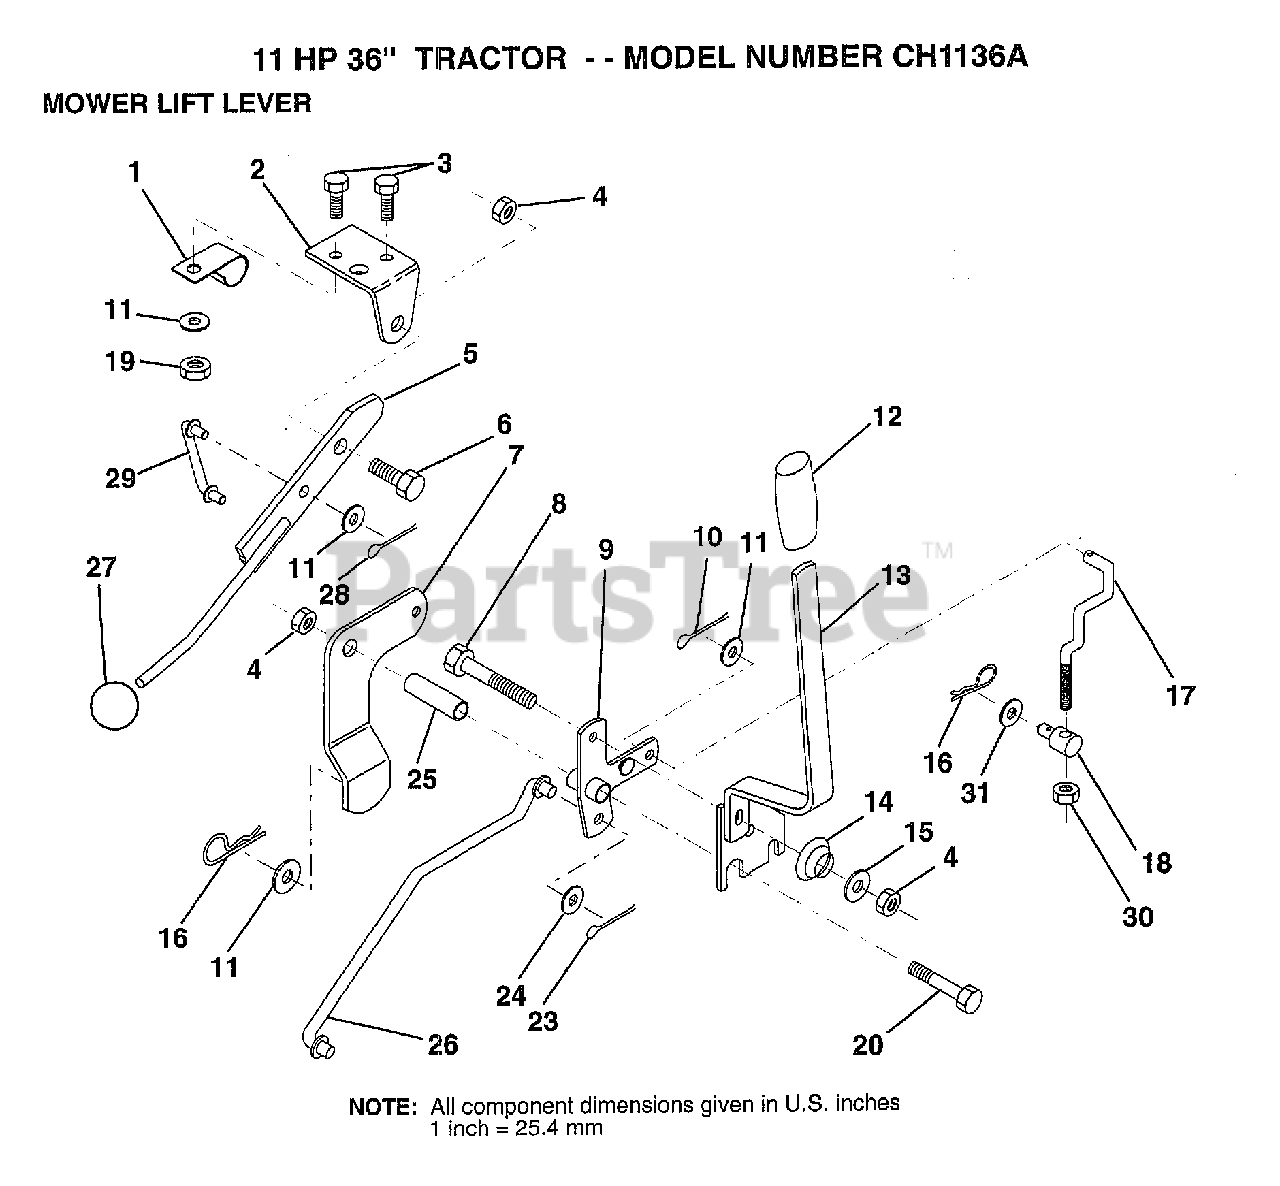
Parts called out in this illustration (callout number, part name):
1	"CLIP,INSULATOR"
2	BRKT CLUTCH
3	BOLT
4	NUT
5	CLUTCH LEVER AS
6	"BOLT, SHOULDER LT"
7	MWR CLUTCH ARM AS
8	BOLT
9	"BELLCRANK,LIFT"
10	COTTER PIN
11	WASHER
13	HANDLE.ASM.LIFT
14	SPRING COMPRESSIO
15	WASHER T
16	SPRING.RETAINER
17	"LINK,LIFT FRT"
18	TRUNION
20	BOLT
23	PIN COTTER 1/8
25	TUBE SPACER
26	ROD LIFT MOWER
27	KNOB T(3/8 HOLE)
29	CLUTCH LINK
30	NUT
31	WASHER
